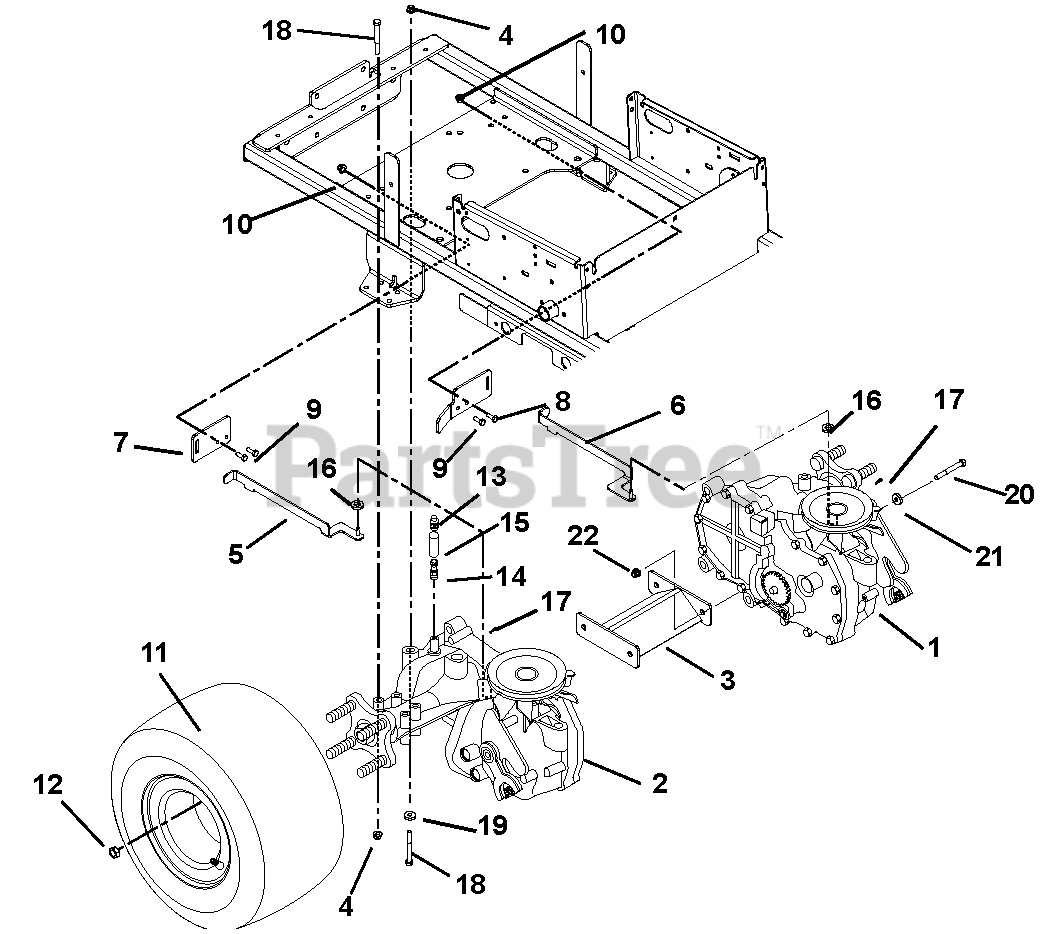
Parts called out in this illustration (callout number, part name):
1	EZT, Left Hand Transaxle-Hydrogear
2	EZT, Right Hand Transaxle-Hydrogear
3	Weldment, Transaxle Support
4	Nut 5/16-18 Flange Nyloc
5	Weldment, Dump Valve (RH)
6	Weldment, Dump Valve (LH)
7	Bracket, Dump Valve
8	Bracket, Dump Valve/Clutch Stop (404)
9	Bolt-Hex .25-20 x .75 Grade 5
10	Nut, Locking Nylon .250-20
11	Assembly, Tire Wheel 18 x 8.5-8 CTR (403)
12	Nut, Lug .50-20
13	Cap, Vent .50
14	Fitting, Straight .50
15	Hose, Vent
16	Washer-Flat-Steel .265 x .50 x .087
17	Pin-Hair-Internal .06 x .18 x .77
18	Bolt, Hex .31-18 x 2.75
19	Washer, Flat Steel .328 x .87 x .179
20	Bolt, Hex .38-16 x 2.50 Grade 5
21	Washer, Flat Steel .406 x 1.00 x .188
22	Nut, .38-16 Nyloc Flange
